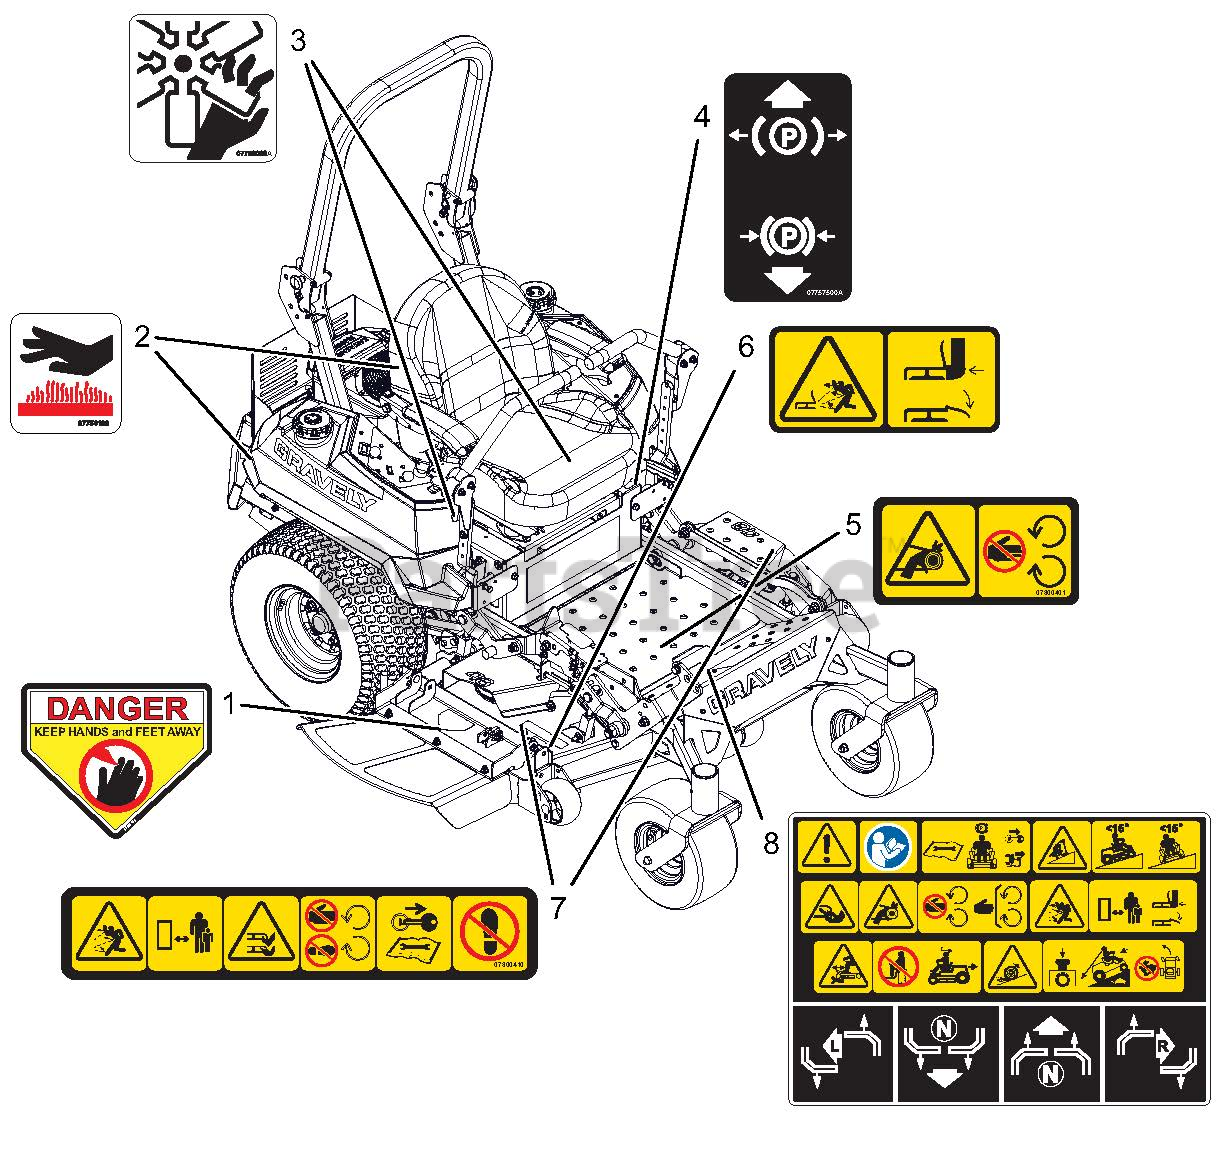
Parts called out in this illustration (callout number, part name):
1	DECAL, DANGER
2	DECAL, HOT SURFACE
3	DECAL, DANGER FAN
4	DECAL, PARKING BRAKE LEVER
5	DECAL, SAFETY - GUARDING
6	DECAL, SAFETY - DECK GUARDING
7	DECAL, DECK SAFETY
8	DECAL, INSTR SAFETY
